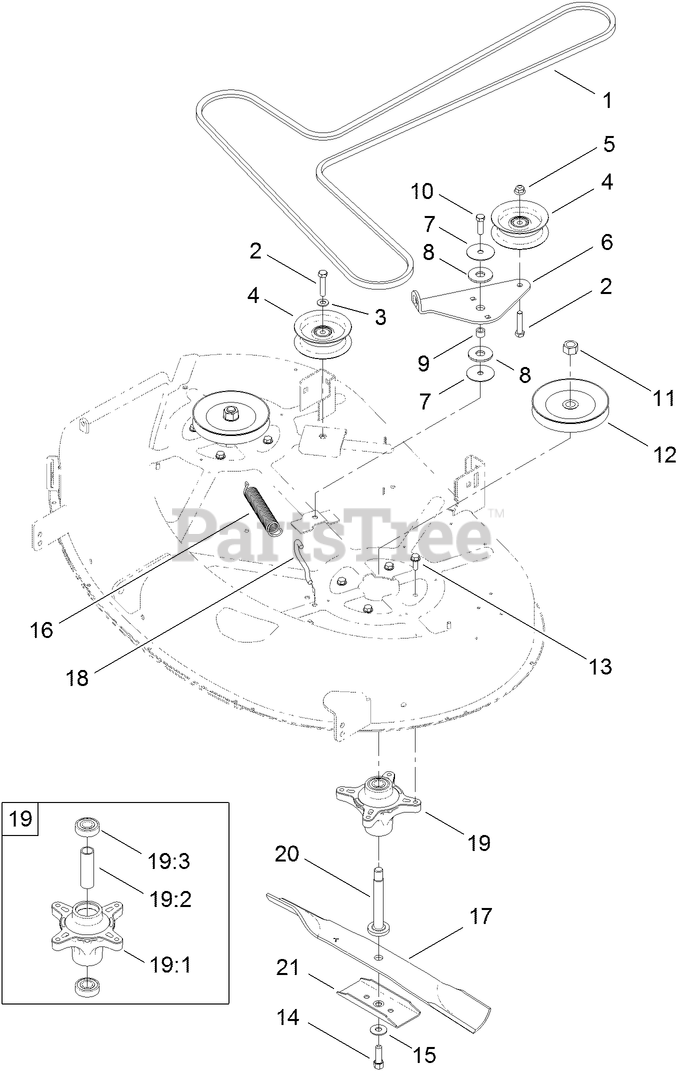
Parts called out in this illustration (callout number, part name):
1	V-BELT
2	SCREW-HH
3	WASHER-FLAT
5	NUT-HF, NI
6	ARM-IDLER
7	WASHER
8	WASHER-FRICTION, COMPOSITE
9	SPACER
10	SCREW-HH
11	NUT-HEX
13	SCREW-TAPTITE
14	SCREW-HH
15	WASHER-BELLEVILLE
16	SPRING-EXTENSION
17	BLADE-21.6 INCH
18	HOOK-RETURN, SPRING
19:2	SPACER
20	SHAFT-SPINDLE
21	STIFFENER-BLADE
